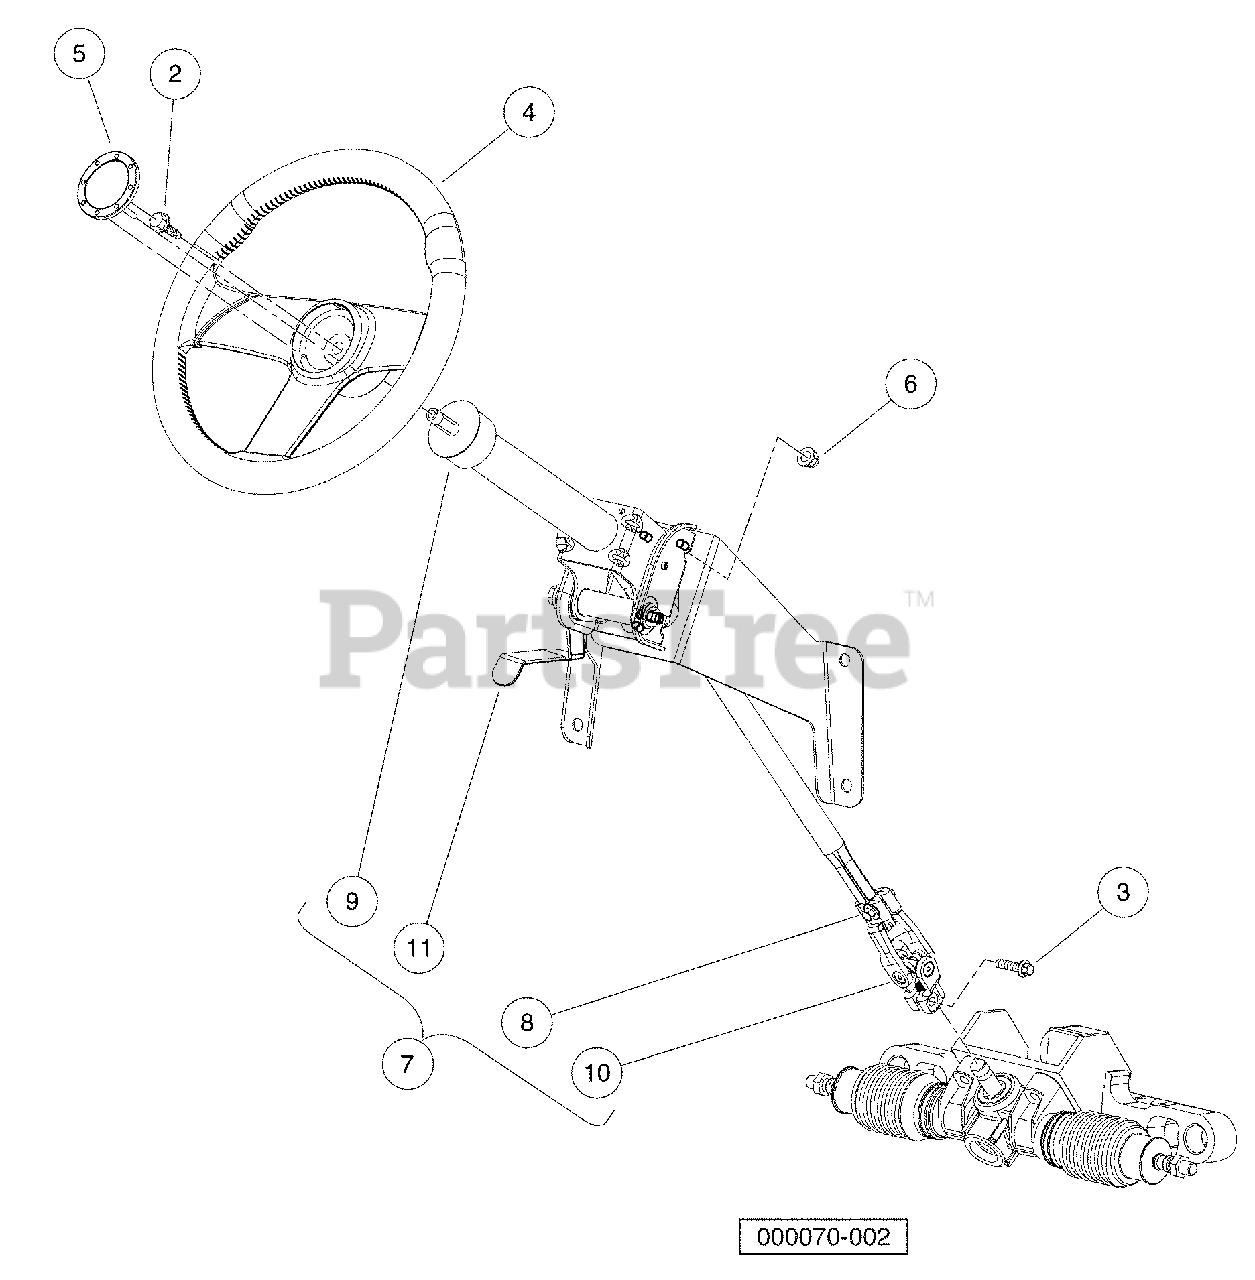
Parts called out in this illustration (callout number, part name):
1	Instl, Steering System
2	Bolt, M10 X 20 Hex Washer Hd
3	Bolt, Flange Head, M8 X 30.0.
4	Steering Wheel, Viper, Hex Hub.
5	Cap, Steering Wheel, Viper
6	Lock Nut, Flg M8 X 1.25 Nylon
7	Steering Column
8	Bolt, Flange Head, M8 X 30.0
9	Shroud, Steering Column.
10	Bolt, M4 X .7 X 60
11	Handle, Steering, Tilt
